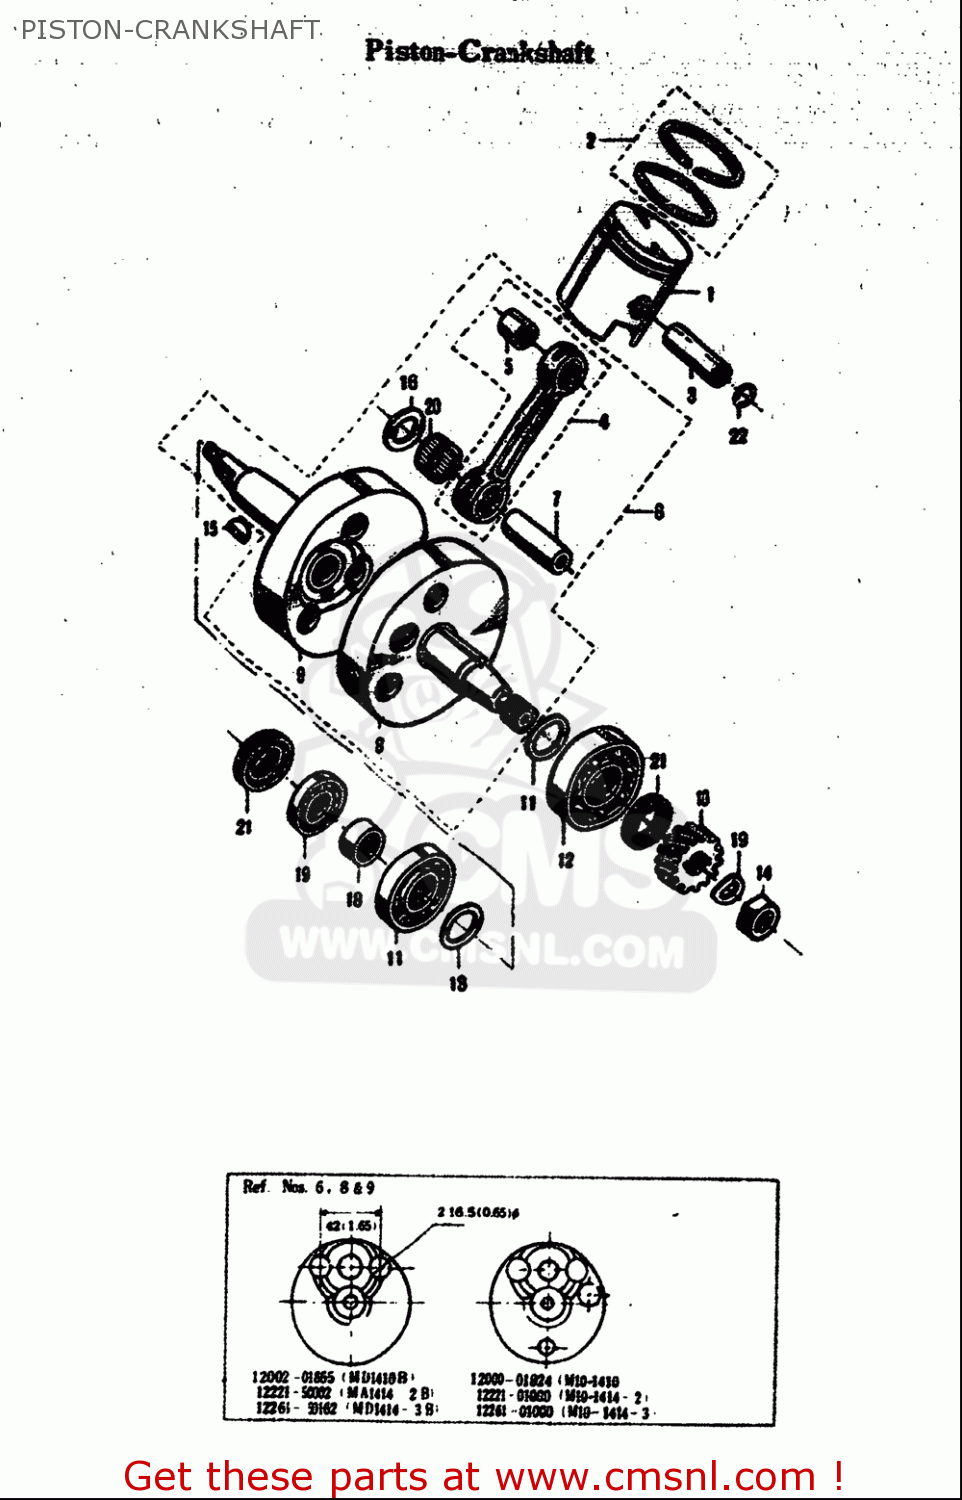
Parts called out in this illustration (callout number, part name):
2	RING SET,PISTON
3	PIN,PISTON
11	BEARING(17X40X12)
12	BEARING
13	SHIM(17X24X0.5)
14	NUT
15	KEY
16	WASHER(16X32X1)
20	BEARING(16X22X11.8)
21	SEAL,OIL(17X29X7)
